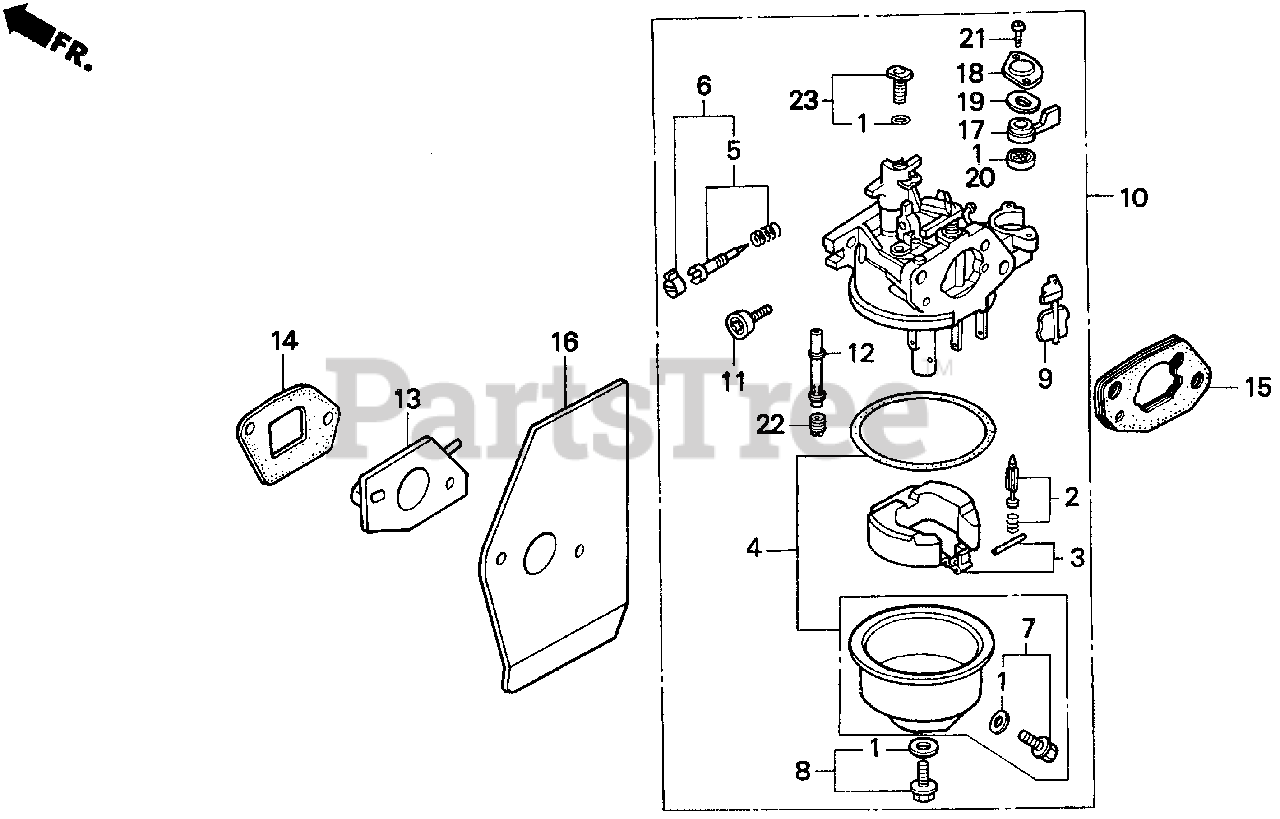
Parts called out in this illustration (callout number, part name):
1	GASKET SET
2	VALVE SET, FLOAT
3	FLOAT SET
4	CHAMBER SET, FLOAT
6	SCREW SET
7	SCREW SET, DRAIN
8	SCREW SET B
9	CHOKE SET
10	CARBURETOR ASSY.
11	SCREW, THROTTLE STOP
12	NOZZLE, MAIN
13	INSULATOR, CARBURETOR
14	GASKET, INSULATOR
15	SPACER, CARBURETOR
16	GASKET, CARBURETOR
17	LEVER, VALVE
18	PLATE, LEVER SETTING
19	SPRING, VALVE LEVER
20	GASKET, VALVE
21	SCREW, PAN (3X6)
22	JET, MAIN (#65)
22	JET, MAIN (#68)
22	JET, MAIN (#62)
23	JET SET, PILOT (#40)
